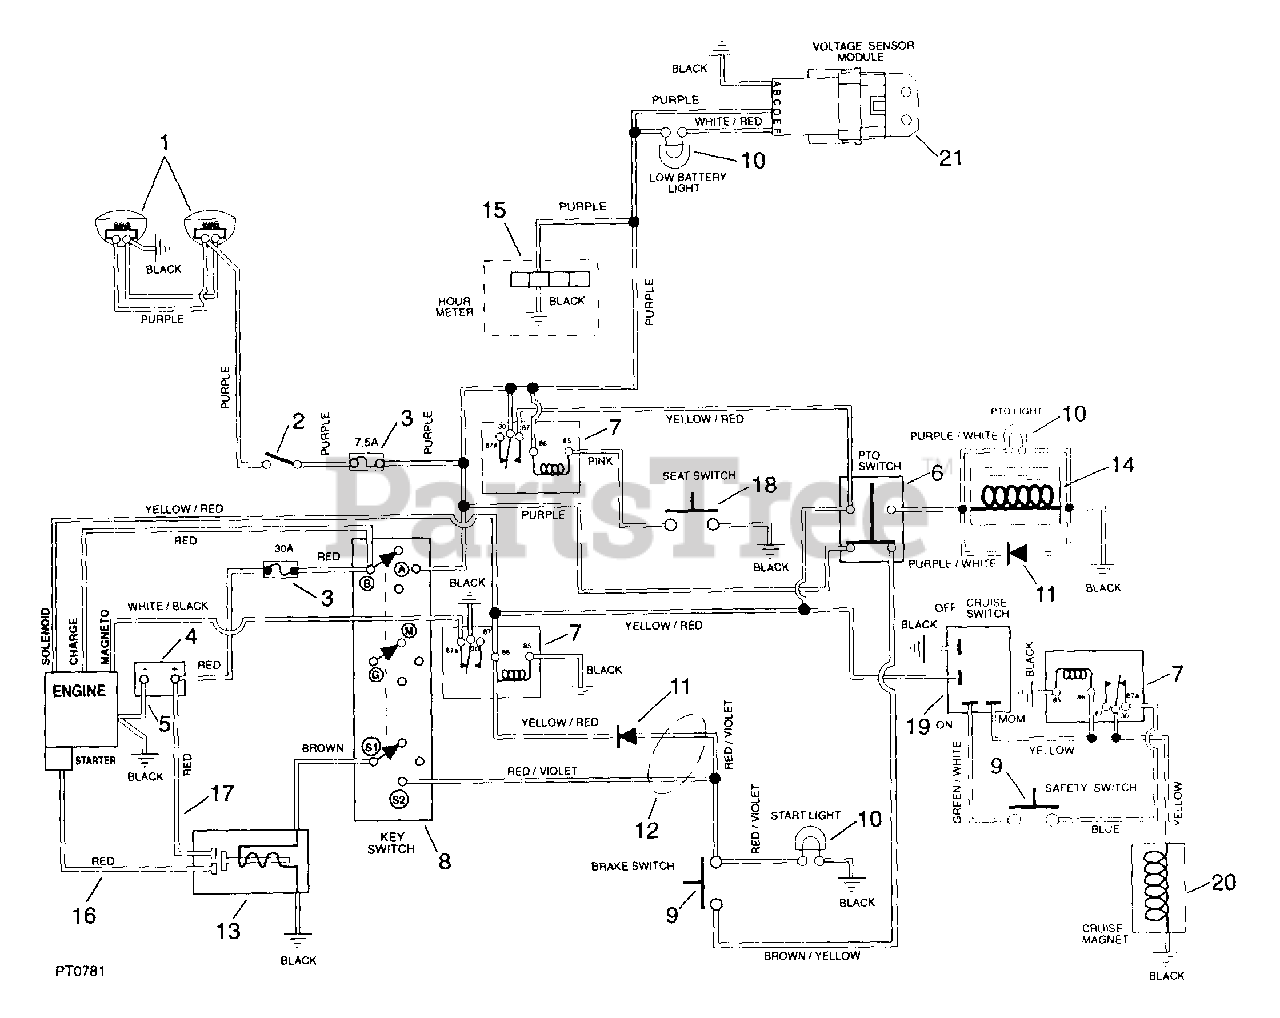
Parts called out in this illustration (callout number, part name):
1	HEADLIGHT- RH
1	HEADLIGHT- LH
2	SWITCH - LIGHT
3	7.5 AMP Fuse
3	30 AMP Fuse
4	BATTERY W/TUBE
5	GROUND CABLE .31X22.00X.31
6	PTO KNOB/ SWITCH ASSY
7	RELAY
8	KEY SWITCH
9	SWITCH- SINGLE POLE N.O.
10	#194 Bulb
11	MOLDED DIODE PLUG 1 AMP
12	WIRE HARNESS - 1640H TEC
13	SOLENOID
14	ELECTRIC CLUTCH/BRAKE (3.4AMP)
15	HOURMETER KIT- SIERRA
16	START CABLE 22"
17	STARTER CABLE 6.75"
18	SWITCH- SEAT
19	SWITCH - CRUISE
21	MODULE - VOLTAGE SENSOR
